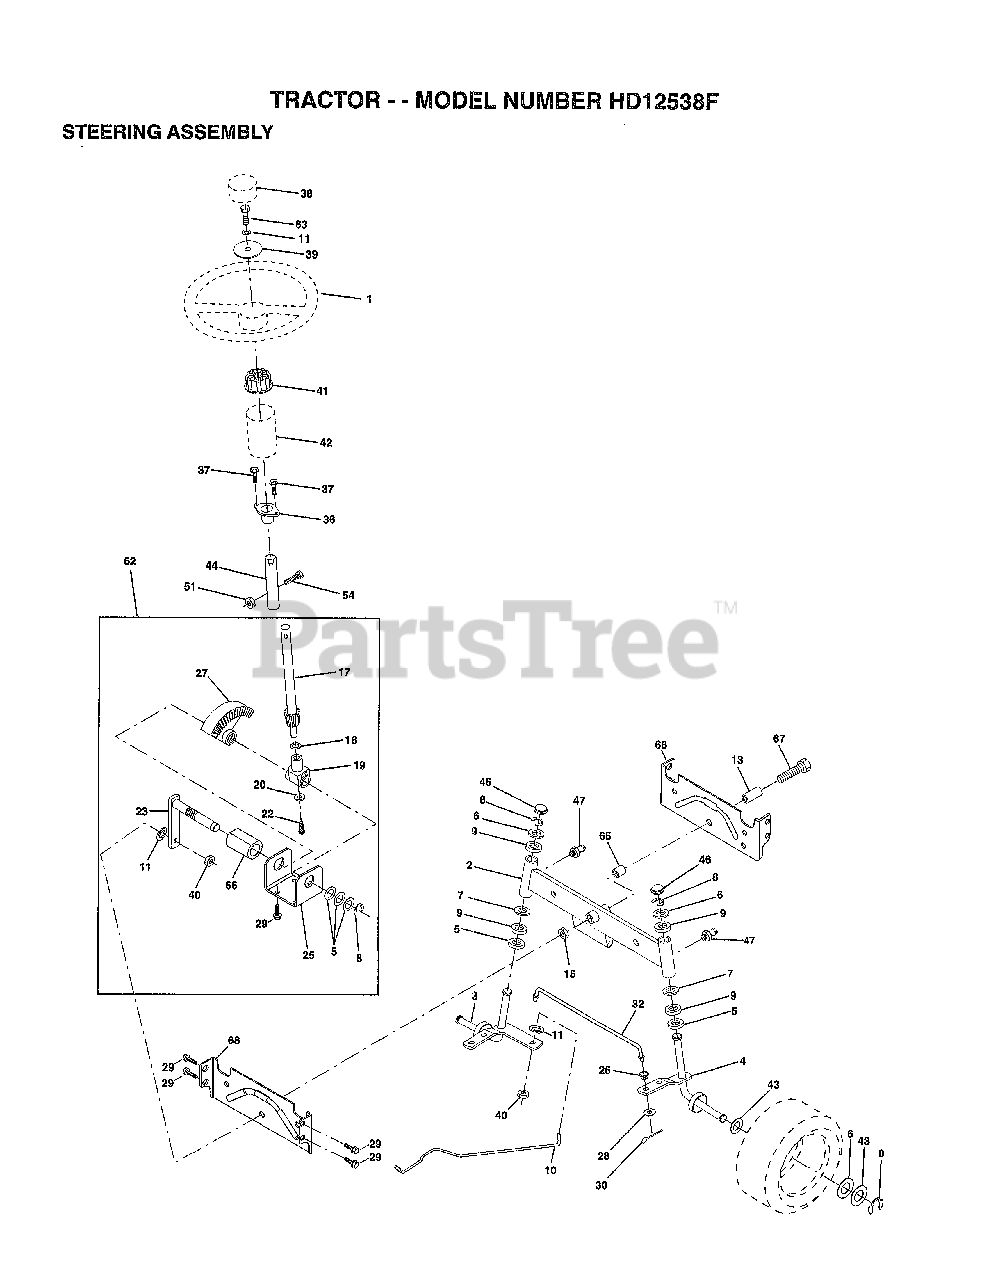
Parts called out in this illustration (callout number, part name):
1	WHEEL STR AYP BLK
2	AXLE ASM
3	SPINDLE.ASM.LH
4	"SPINDLE ASM,RH"
5	WASHER .T
6	WASHER
7	WASHER
8	RING
9	COL. SRTG. BEAR.
10	DRAGLINK-STAMPED
11	LOCKWASHER
13	BEARING AXLE
15	"NUT-LOC,FLANGE LT"
17	SHAFT ASM STEERIN
18	THRUST WASHER
19	SUPPORT.SHAFT
22	SCREW HEX SOC1/4-
25	BRKT-STEERING
26	BUSHING.DRAGLINK
27	GEAR SECTOR
28	WASHER
29	SCREW
30	COTTER PIN
32	TIE ROD
36	BUSHING.STEERING
37	"SCREW-TT,10-32 FL"
38	CAP STEER AYP
39	WASHER T
40	GRIPCO NUT
41	ADAPTER LT
42	BOOT.STEER.PL
44	EXT SHAFT STEERIN
46	CAP
47	ZERK M
51	NUT
54	BOLT
62	KIT STEERING ASM
63	BOLT
65	SPACER AXLE
66	"BEARING-ARM,PITMA"
67	BOLT
68	BRACE AXLE
